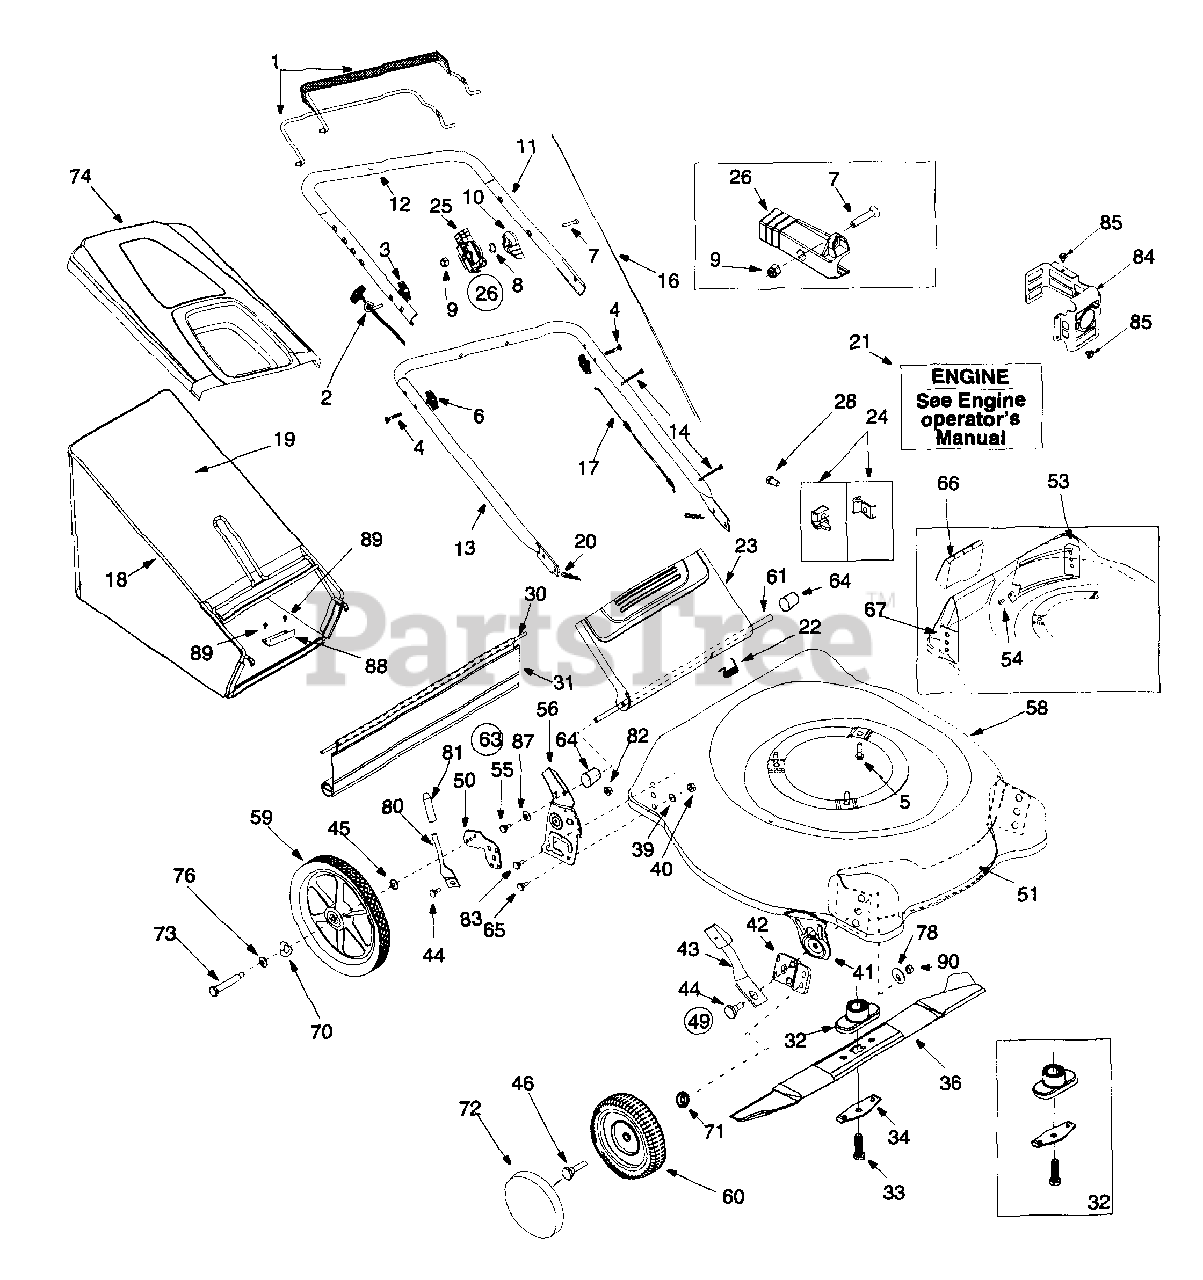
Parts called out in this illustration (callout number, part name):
2	Rope Guide
3	Handle Knob
4	Curved Hd. Bolt 5/16-18 x 2" Lg.
5	Scr. TT. 3/8-16 x 1.00" Lg. HxIndWash.
6	Hand Knob
7	Oval C-Sunk Scr. 1/4-20 x 1.825 Lg.
8	Spring Washer
9	Hex Lock Nut 1/4-20 Thd.
10	Throttle Lever
11	Upper Handle
12	Foam Grip
13	Lower Handle - Tec. Grey
14	Cable Tie
16	Control Cable - 36"
17	Throttle Control Wire - 55"
19	Grass Catcher Bag w/o Icon
20	Hairpin Clip
21	Engine
22	Door Spring
25	Throttle Body
26	Throttle Box - Complete
28	Hex Wash Hd. Scr. #10-32 x .62 Lg.
30	Wire Rod
31	Rear Flap
32	Blade Adapter Kit
33	Hex Bolt 3/8-24 x 1.5 Lg.
34	Blade Bell Support
36	21" Blade (Std.)
39	Bell Washer .39 I.D. x 1.38 I.D.
40	Hex Nut 3/8-16 Thd.
41	Height Adj. Plate
43	Spring Lever, Front Wheel
44	Shoulder Bolt, .5" Dia. x .357"
45	Bell Wash. .38" I.D. x .88" O.D.
46	Front Axle Bolt
49	Height Adjuster Ass'y Comp. - R.H.
50	Pivot Bar - R.H.
54	Torx Mach.Ab-Tap Scr. 1/4-14 x .625.
55	Scr. TT. 1/4-20 x .500 HxIndWash.
60	Fr. Wheel Ass'y. 8 x 1.75 Slot Bar Grey
61	Chute Door Pivot Rod
63	Handle Bracket Assembly. - R.H.
64	Spacer .375 O.D. x .50 I.D. x 1.02" Lg
65	Hx Hd Cap Scr. 3/8-16 x .75 Lg.
66	Rear Mulch Plug
70	Wave Washer
71	Spring Washer
72	Hub Cap, Radial, Beige
73	Rear Axle Bolt
74	Hardtop Cover w/Logo
76	Flat Washer
78	Bell Washer
80	Spring Lever, Rear
81	Foam Grip
82	Hex Flange Lock Nut, 3/8-16 Thd.
83	Scr. AB 1/4-14 x .625 HxIndWash.
84	Muffler Guard
85	Screw #10-16 x 3/8" Lg.
87	Bell Washer .265 x ..75 x .062
90	Hex Nut 3/8-16 Thd.
